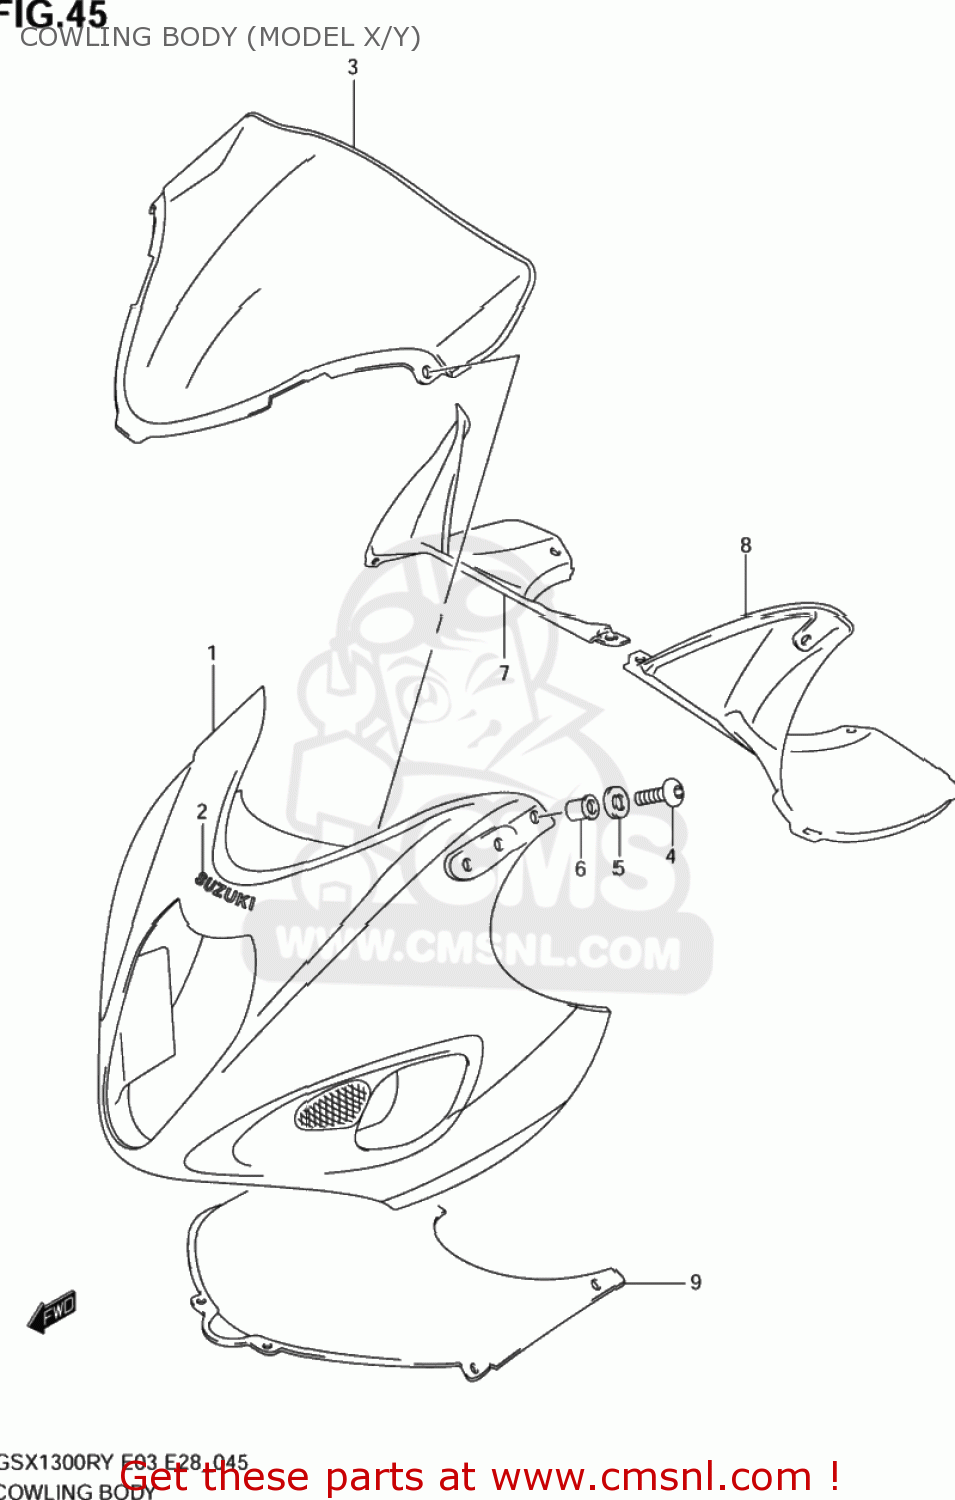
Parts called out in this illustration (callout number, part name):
1	COWLING ASSEMBLY,BODY
2	EMBLEM,SUZUKI
3	WINDSCREEN
4	SCREW(5X14)
5	WASHER
6	NUT
7	PANEL,UPR,R
8	PANEL,UPR,L
9	COVER,BODY COWLING
